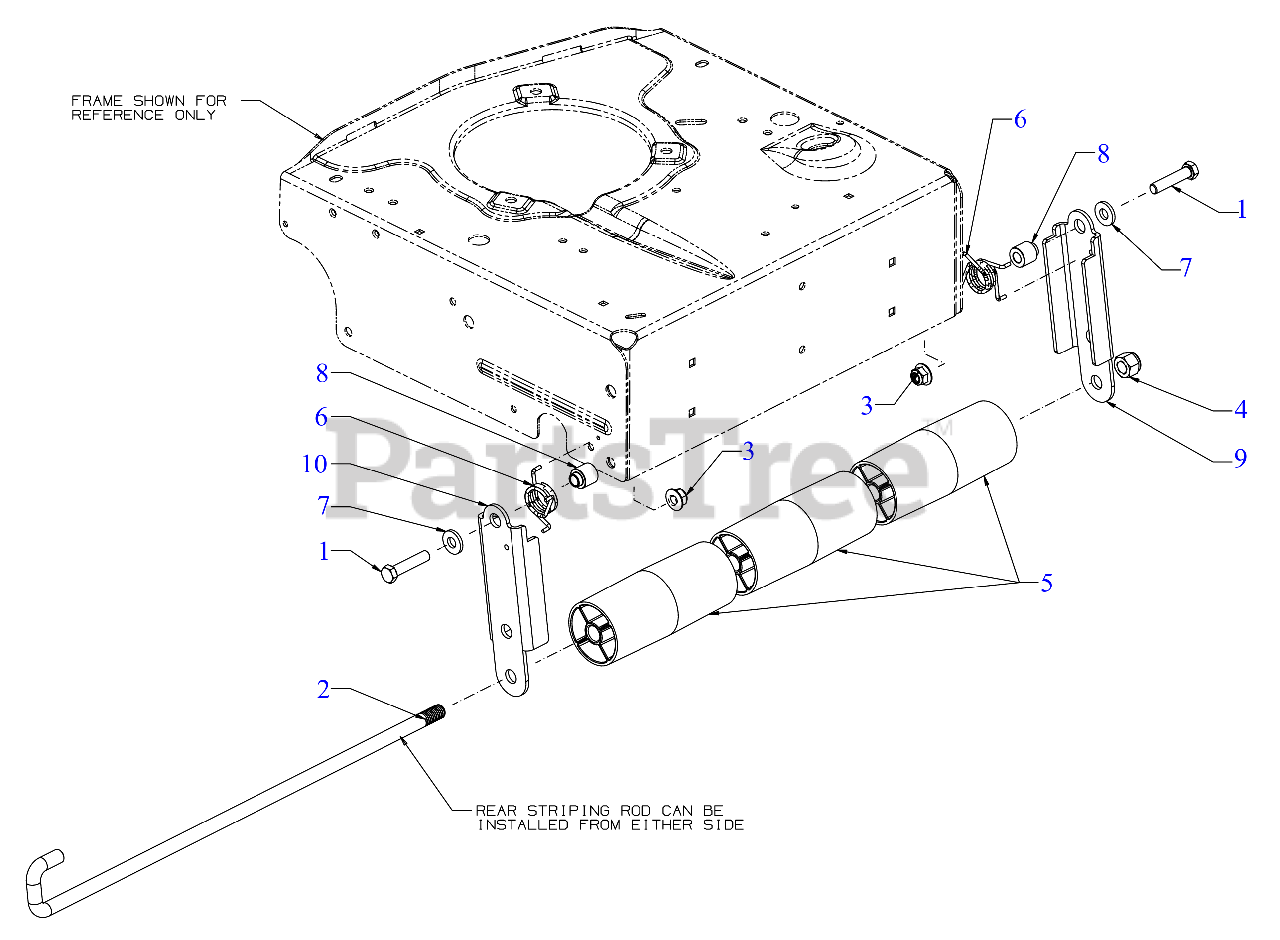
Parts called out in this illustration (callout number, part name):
1	HEX SCREW 3/8-16 x 1.75 GR5
4	HEX LOCK NUT NYLON
6	TORSION SPRING
7	FLAT WASHER
